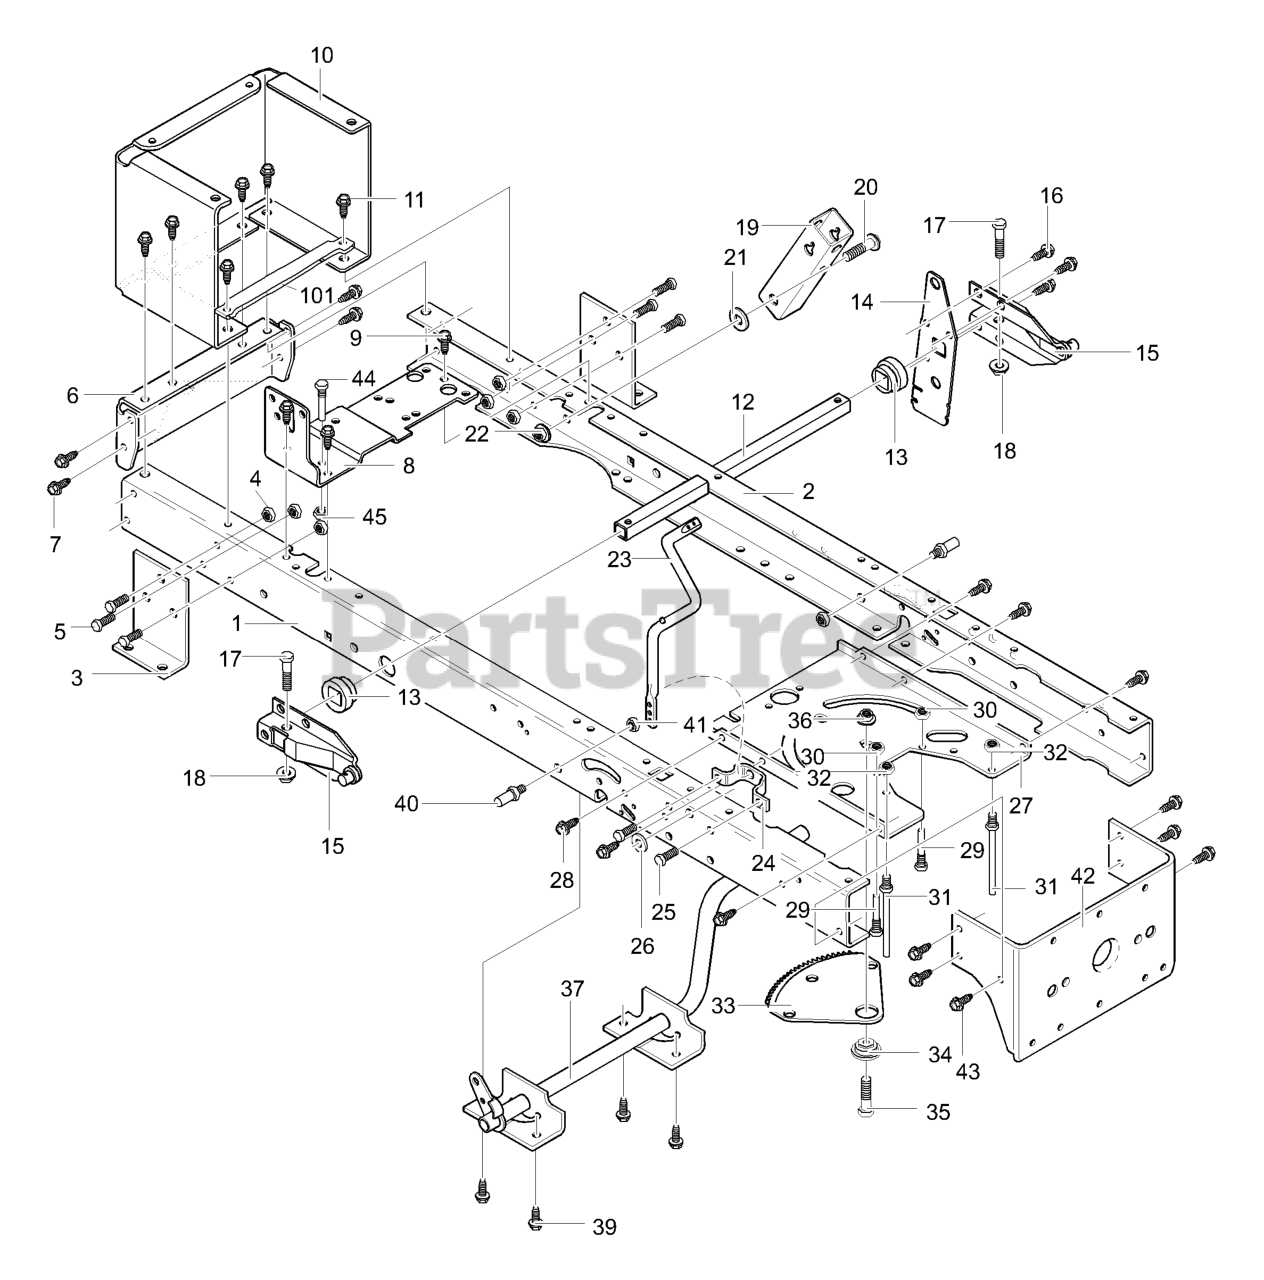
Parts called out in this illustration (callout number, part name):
1	Frame, Rail RH
2	Frame, Rail LH
3	Bracket, Transaxle
4	Nut, .32-18 Flange Ctrlk
5	Screw, .312-18x.75
7	Screw , .312-18x.75
8	Bracket, Shift RH
9	Screw , .312-18x.75
10	Rear Panel
11	Screw , .312-18x.75
12	Lifter Tube
13	Bushing, Lift Arm
14	Plate, Lift Arm
15	Lever, Lift Arm
16	Screw .31x.50
17	Screw, .5/16-21x1.25
18	Nut, .32-24 Flangelock
19	Pivot Bracket
20	Bolt, 3/8 HHSH
21	Flat washer
22	Nut, .38-16 Flange Ctrlk
23	PTO Crank
24	Bracket, Bell Crank
25	Screw, .312-18x.75
26	Flat washer
27	Steering Plate
28	Screw, .312-18x.75
29	Screw Guide 5/16-18
30	Nut, .32-18 Flangelock
31	Screw Guide
32	Nut, .32-18 Flangelock
33	Gear Sector
34	Bearing, Sector Gear
35	CAPSCREW, Hex Head, 5/16-18 x 1
36	Nut, 5/16 Hkeps
37	Asm. Brake Pedal
39	Screw, .312-18x.75
40	Pin, Threaded Shoulder
41	Nut, 3/8-16 Hwdfl Whiz
42	Bracket, Hanger Rear
43	Screw, .312-18x.75
44	Screw Guide 5/16-18
45	Nut, .32-18 Flangelock
93	Flat washer
101	Bracket, Battery Support
